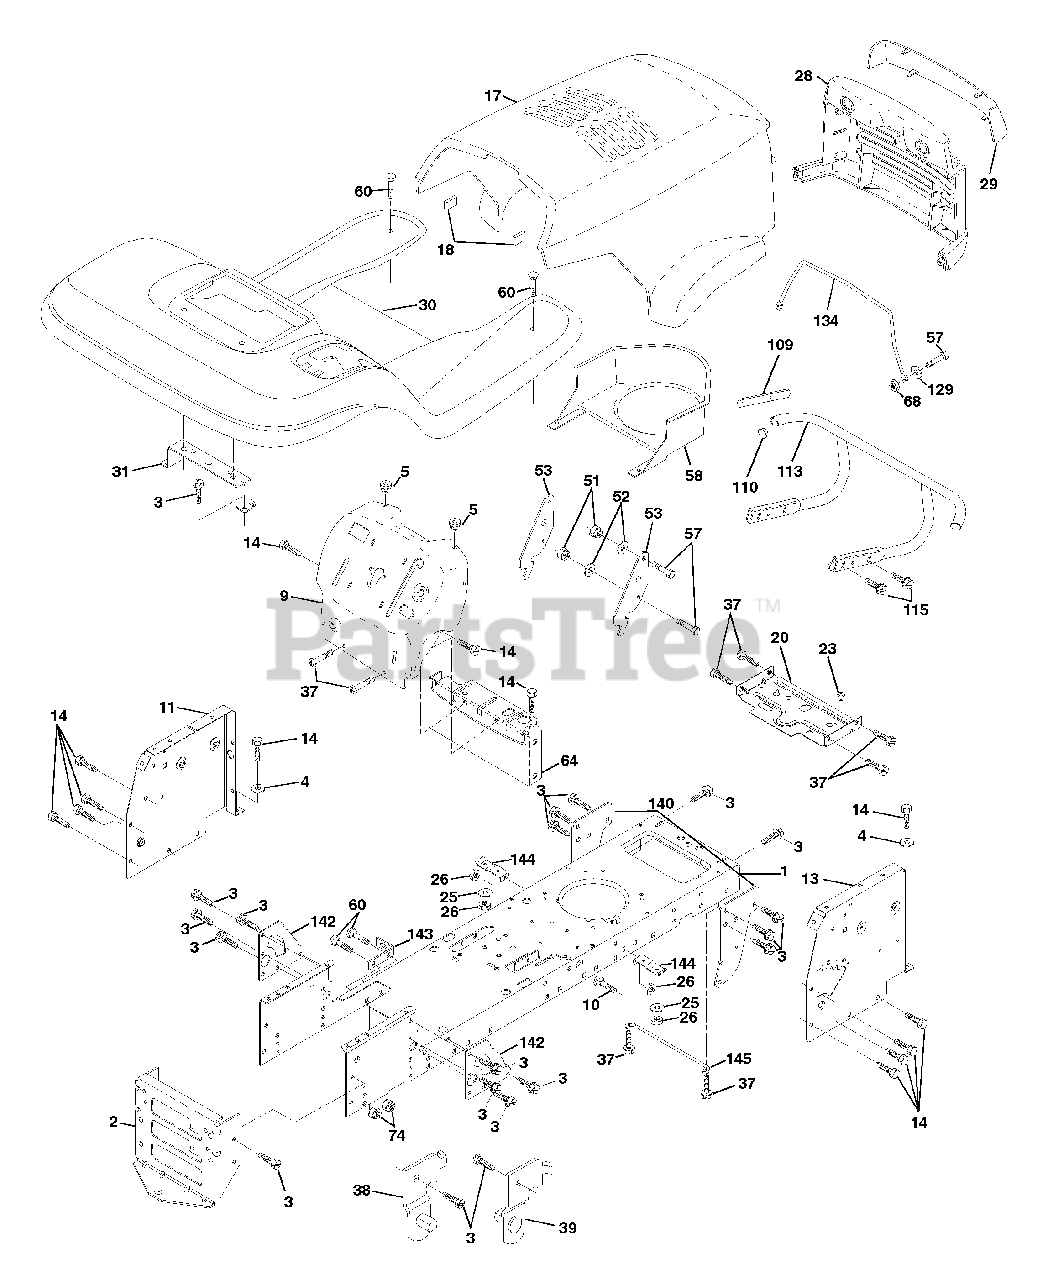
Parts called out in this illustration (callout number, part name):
1	Chassis Weldment
2	Drawbar, Stretch
3	Screw Thdrol 3/8-16 x 3/4 Ty-tt
4	Washer 13/32 x 3/4 x 16 Ga.
5	Bumper Hood/Dash
9	Dash Slkscr.Plm.E.A.Hm.Nc.Sym
10	Bolt Carriage 3/8-16 x 1
11	Panel Dash Lh
13	Panel Dash Rh
14	Screw Thdrol 3/8-16 x 1/2 Ty-tt
17	Hood LT/PL Husqvarna
18	Bumper Hood
20	Plate Mtg Battery Fuel Tank Fr
25	Washer 13/32 X 13/16 X 12 Ga
26	Nut Lock Hex W/Ins 3/8-16 Unc
28	Grille LT/PL Husqvarna
29	Lens LT/PL Husqvarna
30	Fender Footrest STLT Pnt
31	Bracket Support Fender
37	Screw Thdrol 6/16-18 x 1/2 TYT
38	Bracket, Asm. Pivot, L.H., Mower Rear
39	Bracket, Asm. Pivot, R.H., Mower Rear
51	Nut Lock Hex W/Ins 1/4-20
52	Washer 9/32 x 7/8 x 16 Ga.
53	Bracket Pnt. Pick off LT/PL Husqvarna
57	Bolt Hex 1/4-20 x 3/4
58	Air Duct Engine P/L
60	Bolt Rdhd Sqnk 3/8-16 unc x 3/4
64	Dash Lower STLT
68	Nut Keps Hex 1/4-20 unc
71	Nut Crownlock 1/4-20 UNC
74	Nut Crownlock 3/8-16 UNC
109	Bracket Extension Bumper
110	Plug Plastic
113	Bumper Asm.
115	Screw Thdrol 3/8-16 x 1-1/4
122	Bracket Shift Stlt
123	Screw TT #10-32.5.3/8 Flange
129	Washer 9/32 x 5/8 x 16 Ga.
134	Rod Support Hood LT/PL Husq.
140	Bracket Suspension Front
142	Plate Reinforcement STLT
143	Bracket Swaybar Chassis
144	Bracket Pnt Footrest STLT
145	Rod Pivot Chassis/Hood
147	Bolt Hex Hd 1/4-20 UNC 3/4
